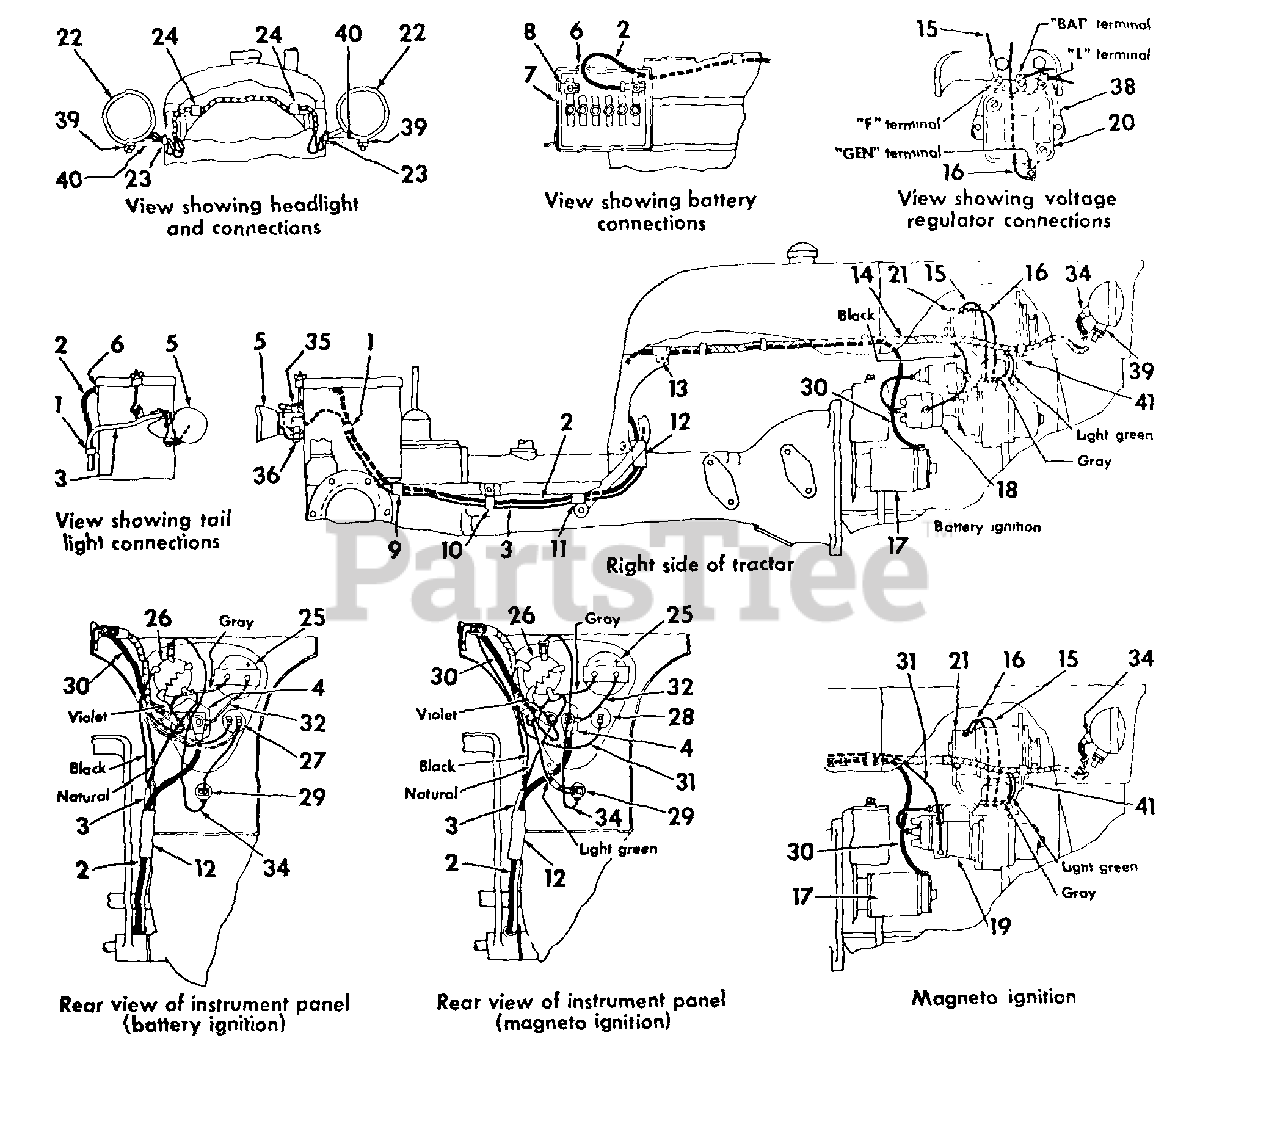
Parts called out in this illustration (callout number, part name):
1	STRAP, CABLE WRAPPING
2	CABLE, BATTERY TO STARTING SWITCH
3	CABLE ASSY, REAR LIGHT
4	SWITCH ASSY, STARTING
5	LIGHT ASSY, TAIL
6	GROMMET, BATTERY BOX
7	BATTERY - 12 VOLT
8	STRAP, BATTERY TO GROUND
9	CLIP, CABLE - 1/2 IN. OPENING
9	CLIP, CABLE - 7/8 IN. OPENING
10	CLIP, THIRD BOLT FROM REAR - 7/8 IN. OPENING
11	STRAP, CABLE WRAPPING
12	CLIP, INSIDE RIGHT SIDE FUEL TANK SUPPORT
13	CLIP, CABLE HARNESS - RH SIDE
14	HARNESS ASSY, CABLE
15	CABLE, GENERATOR
16	CABLE, GENERATOR
17	MOTOR ASSY, CRANKING
18	BATTERY IGNITION UNIT
19	MAGNETO ASSY
20	REGULATOR ASSY, VOLTAGE
21	GENERATOR ASSY
22	LIGHT ASSY, HEAD
23	GROMMET, NO. 6 RUBBER
24	CLIP, HEAD LIGHT CABLE HARNESS
25	INDICATOR ASSY, CHARGE
26	SWITCH ASSY, LIGHTING - 12 VOLT
27	SWITCH ASSY, BATTERY IGNITION KEY
28	SWITCH ASSY MAGNETO IGNITION KEY
29	HOUSING ASSY, FUSE
30	CABLE, BATTERY TO CRANKING MOTOR
31	CABLE, MAGNETO IGNITION SWITCH TO MAGNETO
32	CABLE ASSY, STARTING SWITCH TO CHARGE INDICATOR, RED
34	BODY, CONNECTOR
35	CLIP, REAR LIGHT CABLE
36	CLIP, TAIL LIGHT CABLE
38	BRACKET, VOLTAGE REGULATOR MOUNTING
39	SPACER, HEAD LIGHT
40	POST, HEAD LIGHT
41	CLIP CABLE HARNESS
